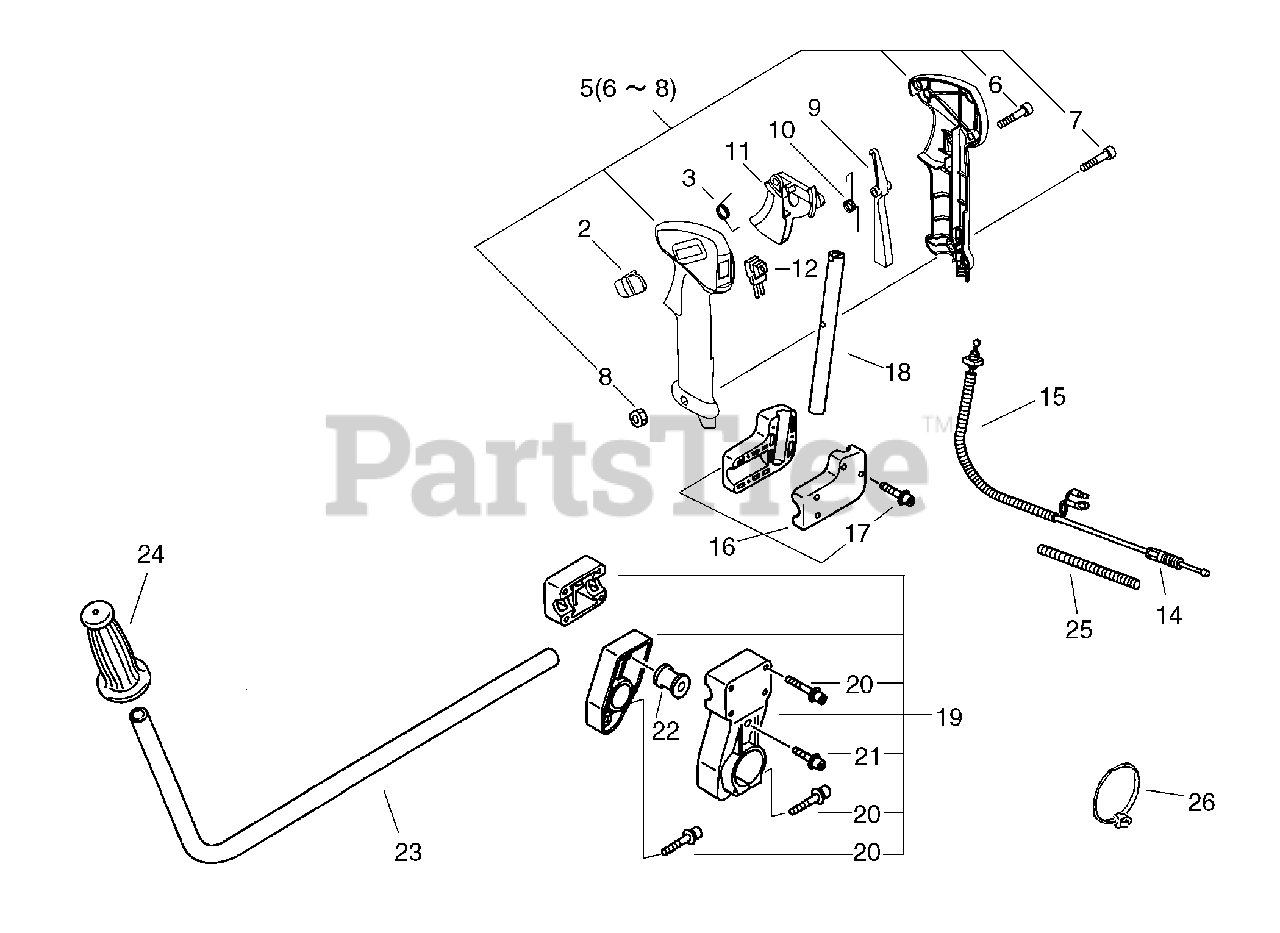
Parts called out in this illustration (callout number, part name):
2	LOCK, THROTTLE
3	SPRING, TRIGGER
5	CONTROL HANDLE ASSY
6	SCREW - 4X16
7	SCREW - 5X30
9	LEVER, TRIGGER LOCKOUT
10	SPRING, LOCKOUT LEVER
11	TRIGGER, THROTTLE
12	SWITCH, IGNITION
14	CABLE, THROTTLE
15	TUBE, PROTECTIVE - CORRUGATED
16	HANDLE BRACKET KIT
17	SCREW - 5X25
18	HANDLE - RIGHT
19	HANDLE BRACKET KIT
20	SCREW - 5X35
21	SCREW - 5X14
23	HANDLE - FRONT
24	GRIP, HANDLE
25	TUBE, PROTECTIVE - CORRUGATED
26	CLAMP
